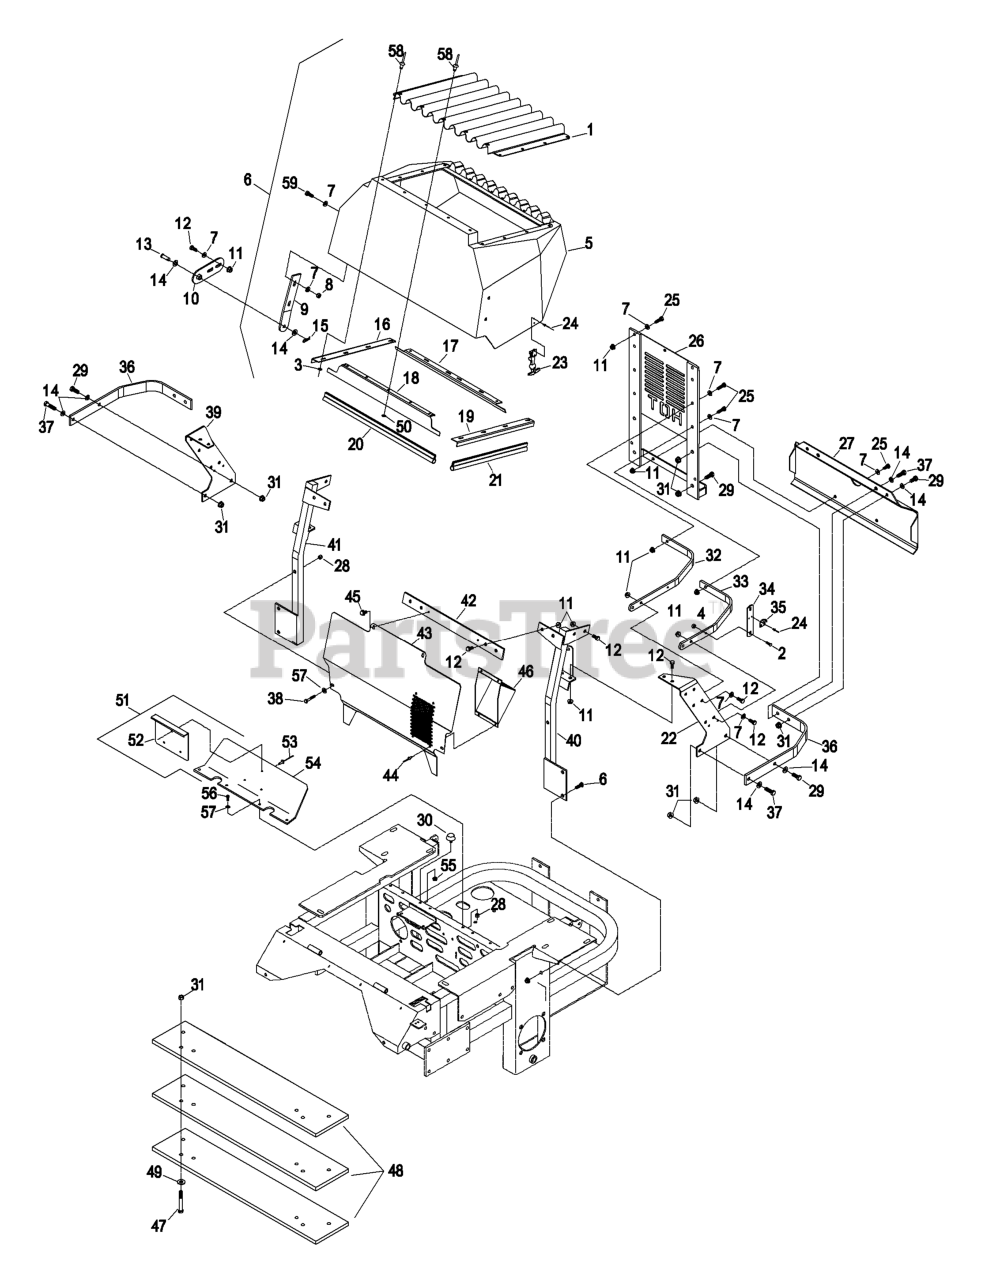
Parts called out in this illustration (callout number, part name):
1	SCREEN-RADIATOR
2	SCREW-HEAD, TRUSS
3	WASHER-FLAT
4	NUT-LOCK, NI
7	WASHER-PLAIN
8	NUT-LOCK, NI
9	PLATE-HINGE, HOOD
10	SHACKLE-HINGE
12	SCREW-HH
13	PIN-CLEVIS
14	WASHER-FLAT
15	PIN-COTTER
16	ANGLE-RADIATOR, RH
17	ANGLE-RADIATOR, BOTTOM
18	ANGLE-RADIATOR, TOP
19	ANGLE-RADIATOR, LH
20	SEAL-TRIM
21	SEAL-TRIM
22	PLATE-SIDE, LH
23	LATCH-RUBBER
25	SCREW-HH
28	NUT-LOCK, NI
29	SCREW-HH
31	NUT-HHF, WHIZ
34	BAR-HOOK, LATCH
37	SCREW-HH
38	SCREW-HH
39	PLATE-SIDE, RH
40	BRACE-RADIATOR, LH
43	DEFLECTOR-AIR
44	RIVET-POP
45	SCREW-HWHTF
46	PLENUM-INTAKE, AIR
47	SCREW-CARR
48	BAR,WEIGHT 38.1#
49	WASHER-BELLEVILLE
50	WASHER-SPRING
53	RIVET-POP
54	SHIELD-ENGINE
56	SCREW-HH
57	WASHER-FLAT
59	SCREW-HH
